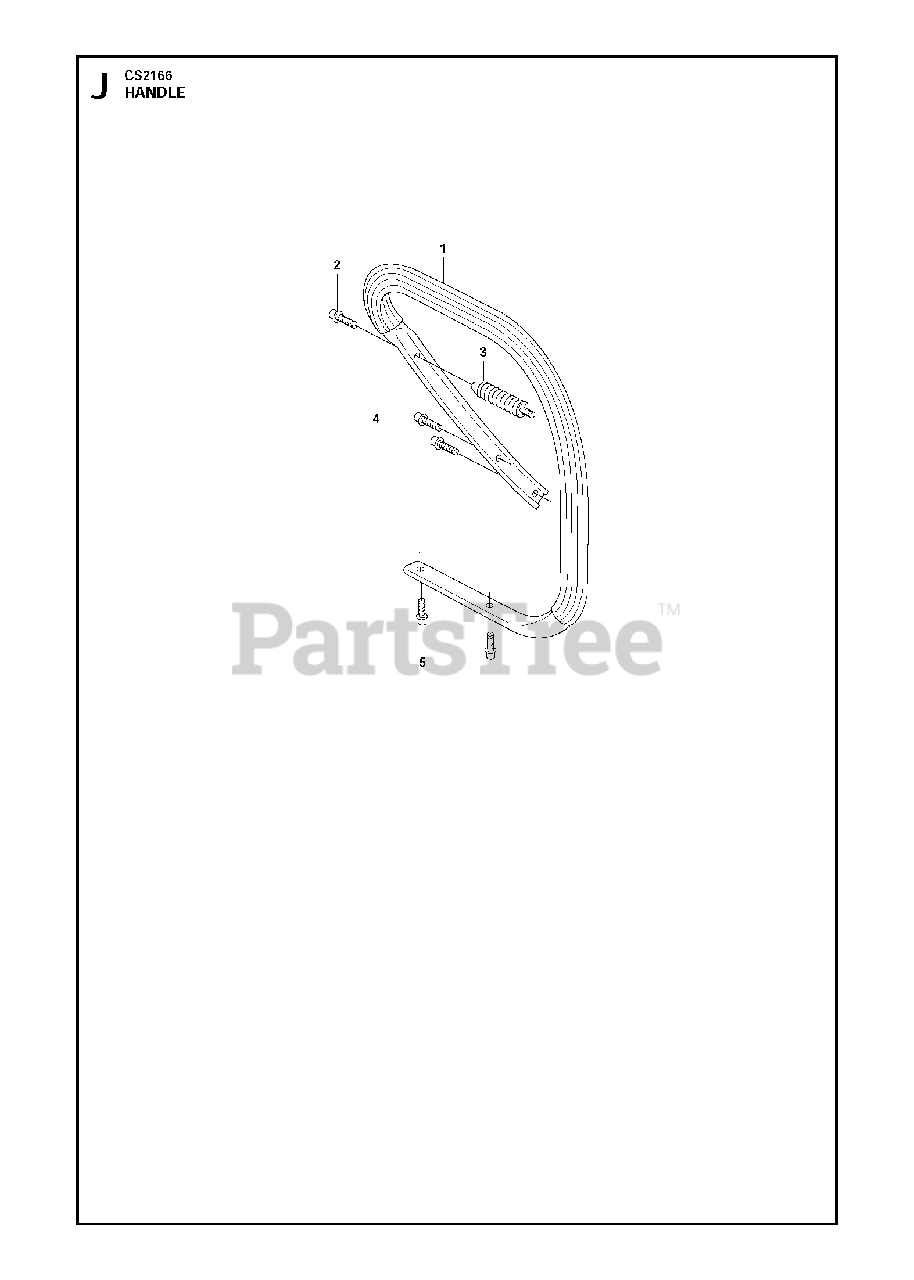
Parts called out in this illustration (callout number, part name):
1	FRONT HANDLE ASSY
3	ANTIVIBE MOUNT
3	VIBRATION ABSORBER
4	SCREW
5	SCREW
